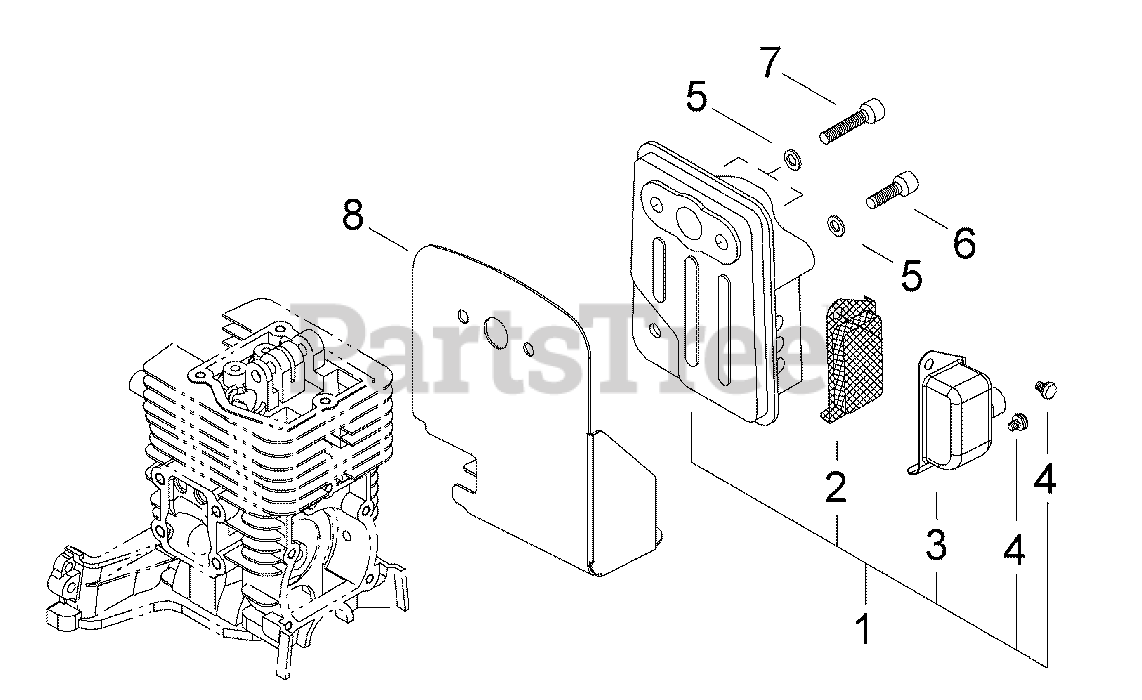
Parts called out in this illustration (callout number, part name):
1	MUFFLER ASSY
2	SCREEN, SPARK ARRESTOR
3	GUIDE, EXHAUST
4	SCREW - 4X6
5	WASHER - 5
6	SCREW - 5X16
7	SCREW - 5X25
8	DEFLECTOR, HEAT
